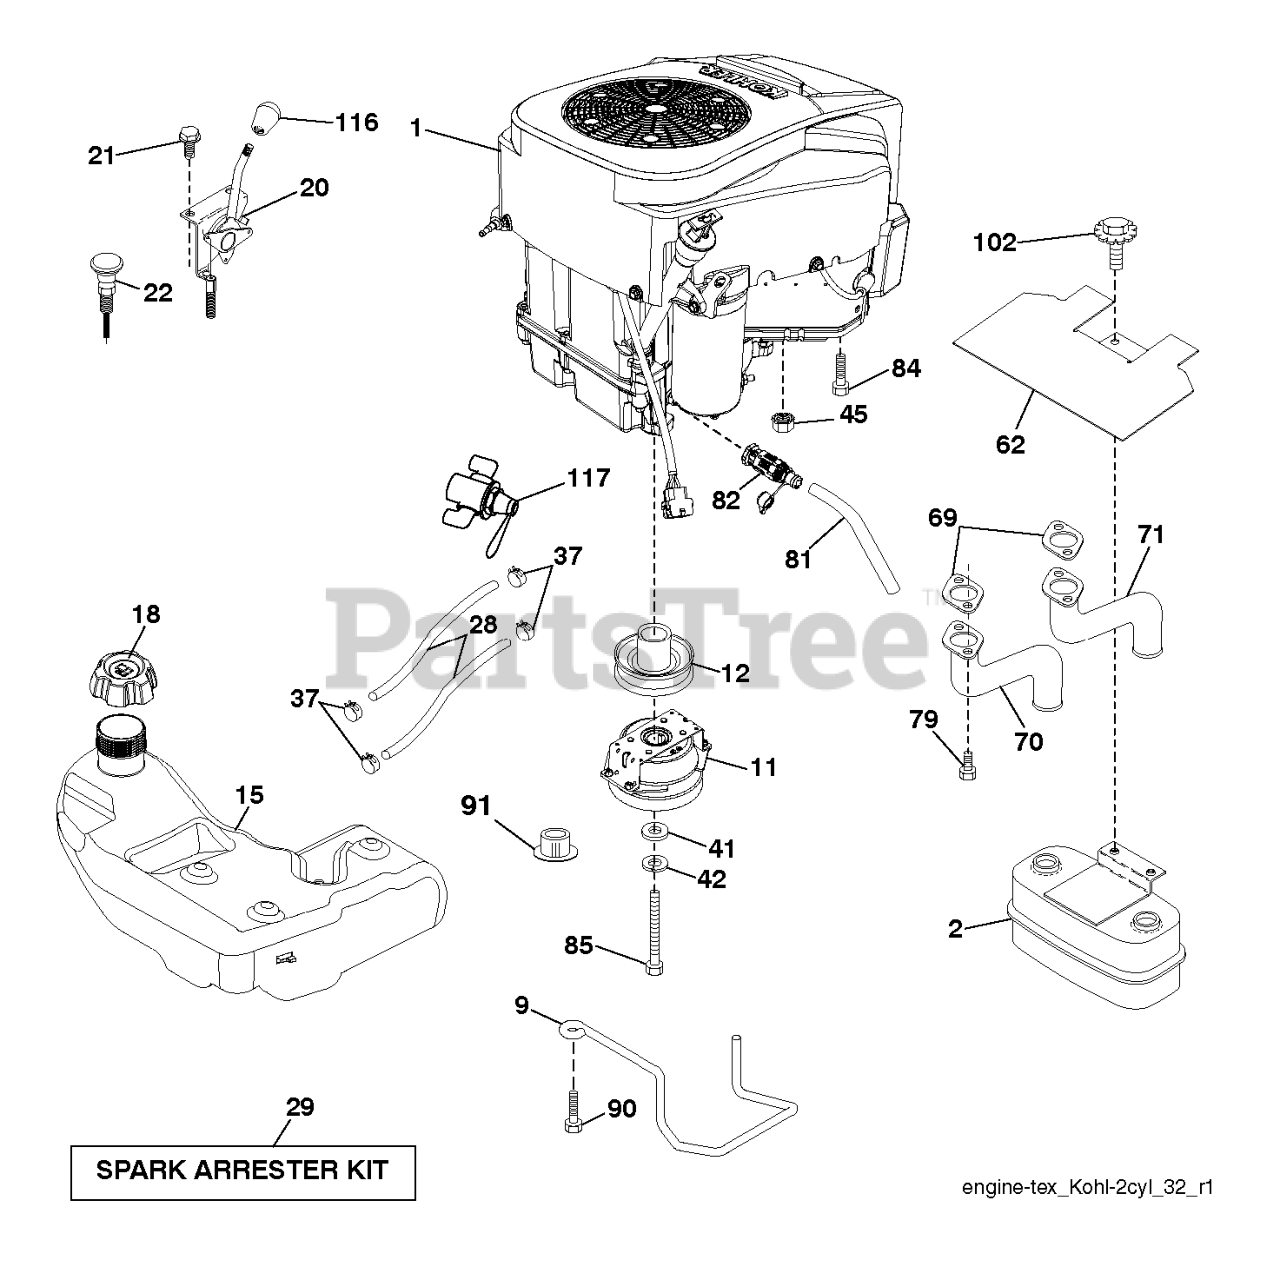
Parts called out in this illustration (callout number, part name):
2	MUFFLER.ASM.TWN.EXTNDED.DFLCTR
9	KEEPER BELT ENGINE
11	CLUTCH.ELECTRIC.LT.48"*
12	PULLEY.ENGINE.TUFFTORQ
15	RP_TANK.ASSY.4.GAL.2.PORT.EPA
18	CAP.ASM.FL.RITCH.3"E10.SYM.498
20	CONTROL.THROTTLE.PRO.KOHLER
21	SCREW.#10 X 0.750.BOS
22	CONTROL.CHOKE.ERGO.PUSH-IN.BLA
28	LINE.FUEL.64"REAR.EMIS
29	KIT.SPARK ARRESTOR 794945 B&S
37	HOSE CLAMP
42	LOCKWASHER
45	NUT
62	SHIELD.HEAT.MUFFLER
69	GASKET.EXHAUST.KOHL.CV18-CV26
70	PIPE.EXHAUST.LH.CV18/20
71	PIPE.EXHAUST.RH.CV18/20
79	SCREW.SOCKET HD.5/16-1
81	TUBE, DRAIN OIL ASM.
82	VALUE.OIL.DRAIN
84	SCREW 3/8-16X1
85	BOLT HEX 7/16-20X4-1/4"
87	BOLT 5/1618UNC X 3/4 W/ SEMS
90	SCREW 3/8-16X1
91	BUSHING.1.375OD
116	KNOB - SHIFT
117	VALVE FUEL RESERVE
